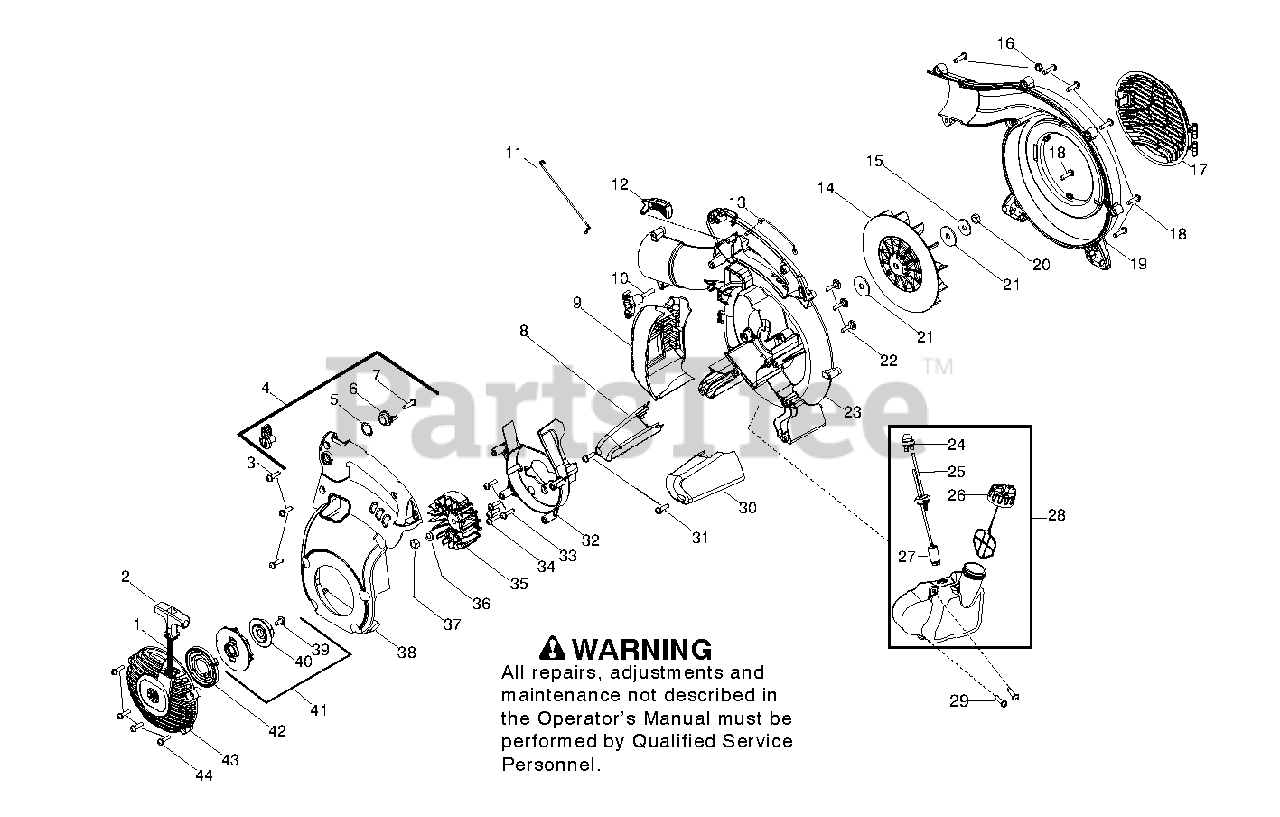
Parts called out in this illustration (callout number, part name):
2	HANDLE - STARTER
4	KIT - CRUIS CONTROL (5,6,7)
6	RATCHET CRUISE CONTROL
8	FOOT - FRONT IMPACT
9	ASSY - MUFFLER GUARD
10	ASSY - TUBE CLAMP
11	WIRE LINKAGE
12	TRIGGER - THROTTLE
13	WIRE, HANDLE GROUND
15	WASHER-FLYWHEEL
17	COVER VAC DOOR BLACK
19	ASSY OUTER SCROLL NON VAC
20	NUT, IMPELLER
21	WASHER IMPELLER
22	SCREW FUEL TANK RETAINER
23	SCROLL - INNER
24	AIR PURGE
25	KIT FUEL LINE GROMMET
26	ASSY - FUEL CAP W/RETAINER
27	FUEL PICK-UP ASSY
28	ASSY - FUEL TANK 26,27,28,29
30	FOOT - REAR IMPACT
32	SCROLL, FLYWHEEL
34	SCREW - SHROUD
35	ASSY, FLYWHEEL
36	WASHER FLAT
37	NUT-FLYWHEEL
38	COVER RED
41	KIT - STARTER
42	SPRING STARTER
43	HOUSING - STARTER COVER
44	SCREW - SHROUD
